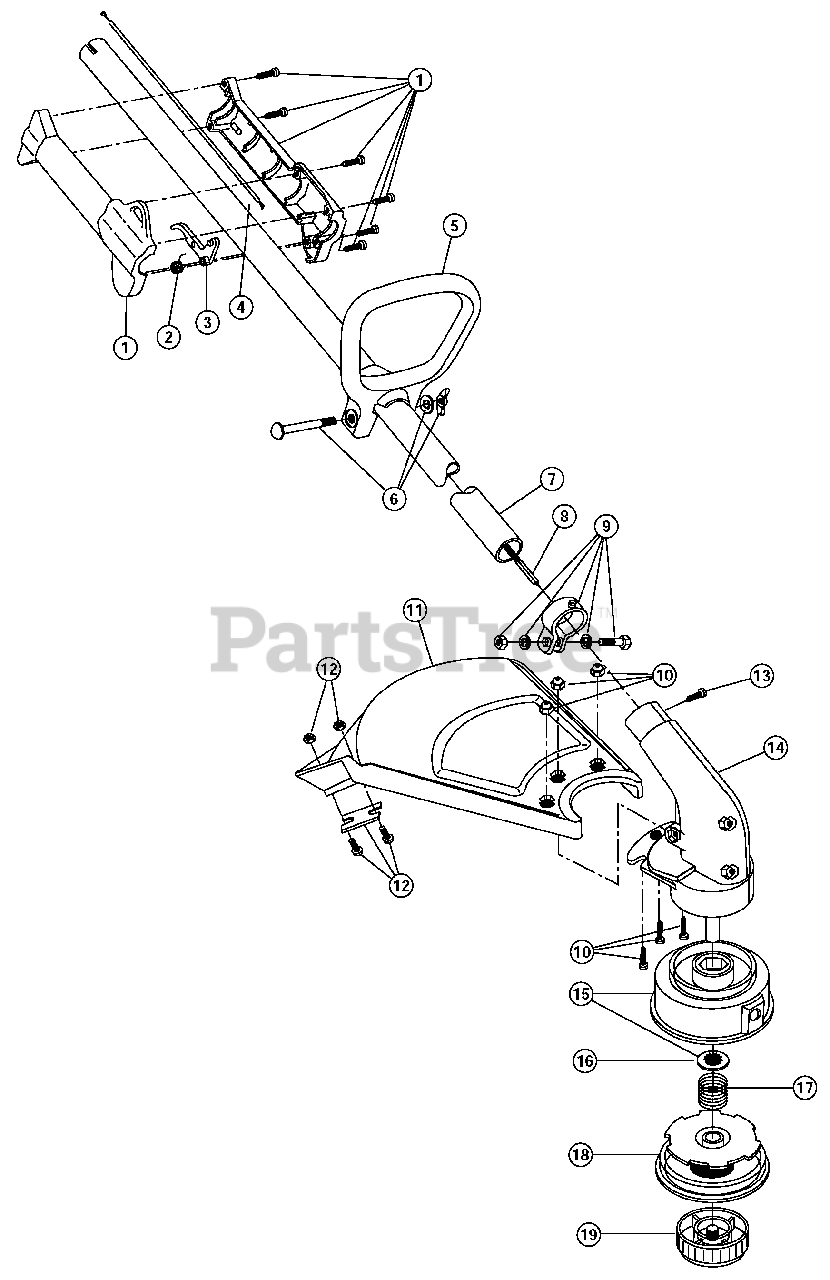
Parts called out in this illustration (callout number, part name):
1	Throttle Housing & Trigger Assembly
2	Throttle Trigger Spring
3	Throttle Trigger
4	Throttle Cable Assembly
5	D-Handle
6	D-Handle Hardware
7	Drive Shaft Housing Assembly
8	Flexible Drive Shaft
9	Lower Clamp Assembly
10	Guard Mounting Screw Assembly
11	Guard and Blade Assembly
12	Blade Assembly
13	Anti-Rotation Screw
14	Gearbox Assembly
15	Outer Spool and Eyelet Assembly
16	Retainer
17	Spring
18	Inner Reel
19	Bump Head Knob Assembly
